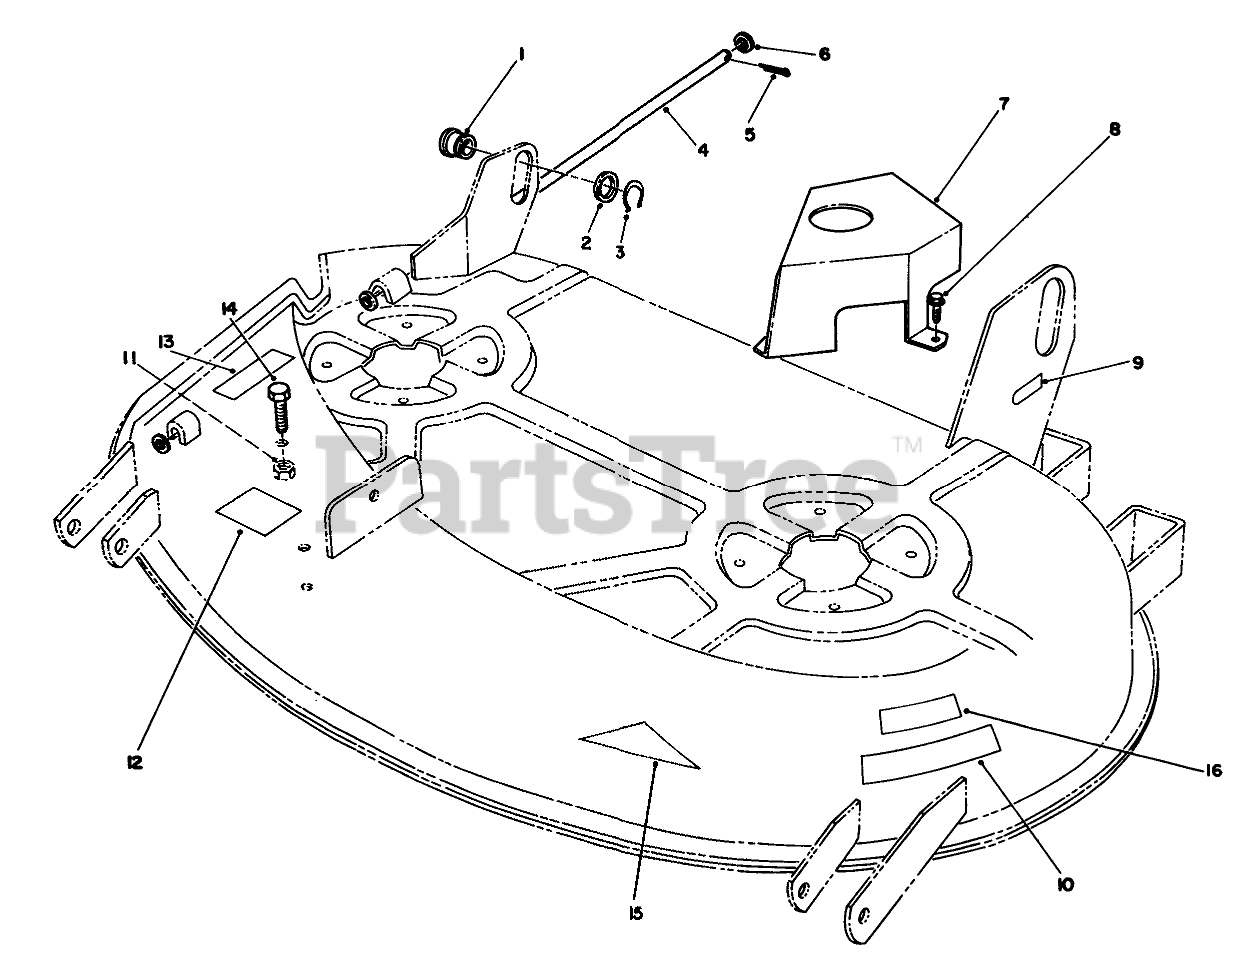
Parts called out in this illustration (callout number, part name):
1	ROLLER-LIFT
2	Washer
3	RING-RETAINING
5	PIN-COTTER
6	WASHER-PLAIN
7	Cover-Belt
8	SCREW-HWHTF
9	Decal-Attach-A-Matic
10	DECAL - DANGER
11	NUT-LOCK, NI
12	Decal-Routing
13	DECAL-DANGER
14	SCREW-HH
15	DECAL-OVERLAY
